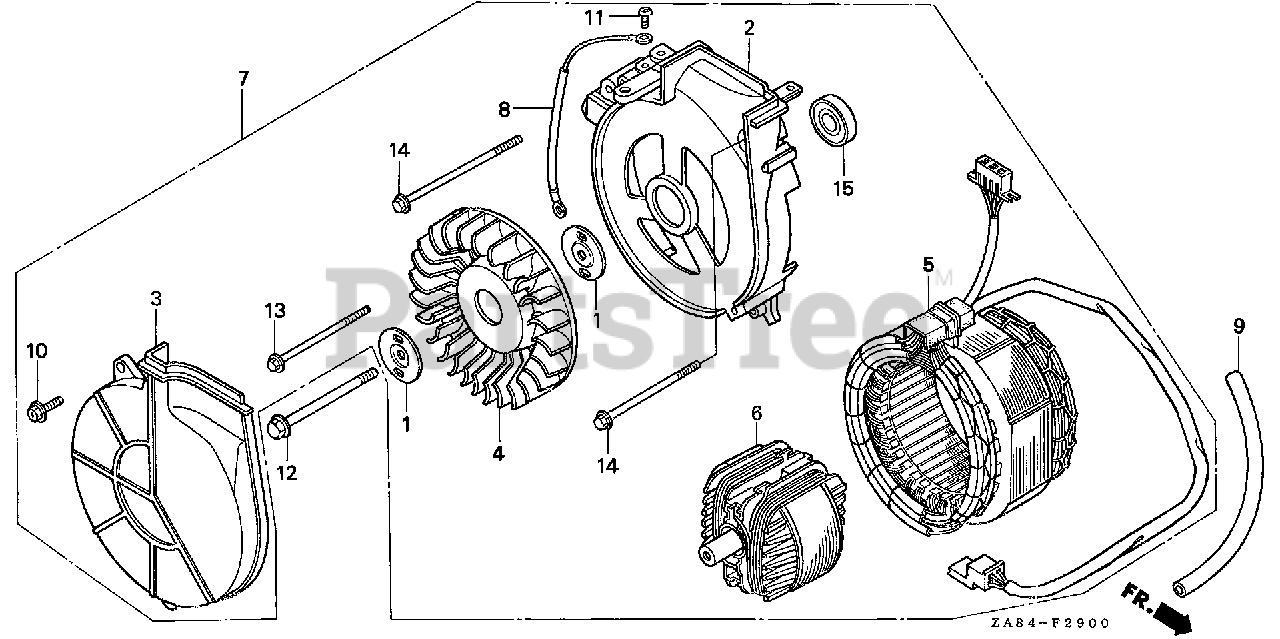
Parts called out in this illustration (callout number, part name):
1	PLATE, FAN SETTING
2	ROTOR SET
2	HOUSING, RR.
3	COVER, GENERATOR FAN
4	FAN, COOLING
5	STATOR ASSY.
6	ROTOR
7	GENERATOR ASSY.
8	WIRE, GROUND
9	TUBE, PROTECTOR (9X100)
10	SCREW, TAPPING (5X12)
11	SCREW, PAN (5X12)
12	BOLT, FLANGE (8X92)
13	BOLT, FLANGE (6X75)
14	BOLT, FLANGE (6X95)
15	BEARING ASSY. (6002)
15	BEARING, RADIAL BALL (6002)
